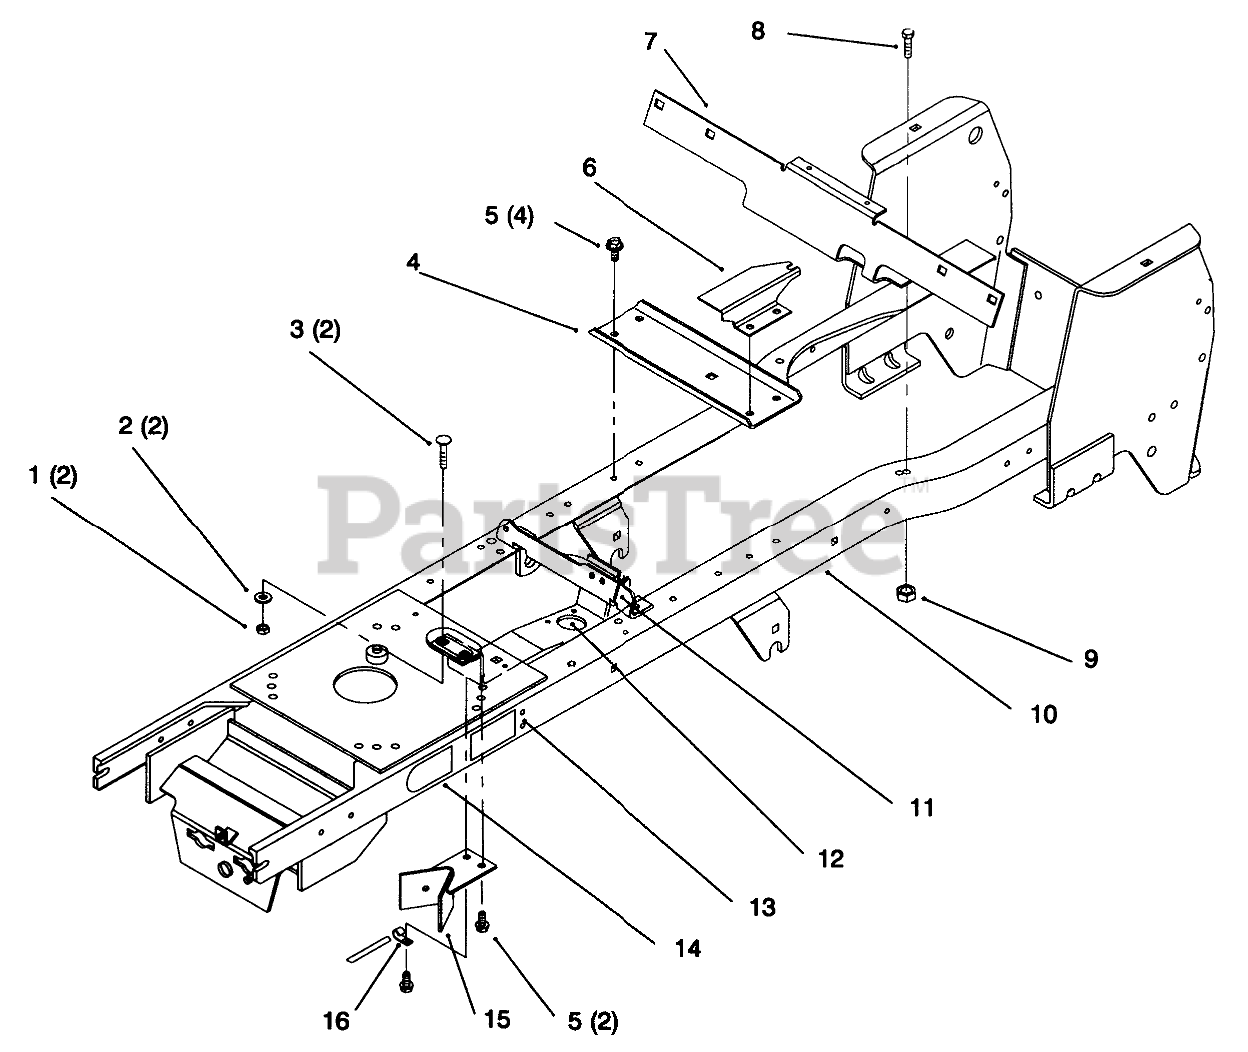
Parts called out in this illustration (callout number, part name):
1	NUT-LOCK, NI
2	WASHER-PLAIN
3	BOLT-CARR
4	BRACKET-IDLER PLATE
5	Screw-HH
6	BRACKET-HOC GAGE
7	SUPPORT - FENDER
8	SCREW-HH
9	NUT-LOCK, NI
10	Frame
11	TIE-CABLE
12	STEERING BRKT WA
13	Decal-Installation (Only On: 72064)
14	DECAL-ATTACH A-MATIC
15	WLDMT-PTO STOP
16	CLIP
